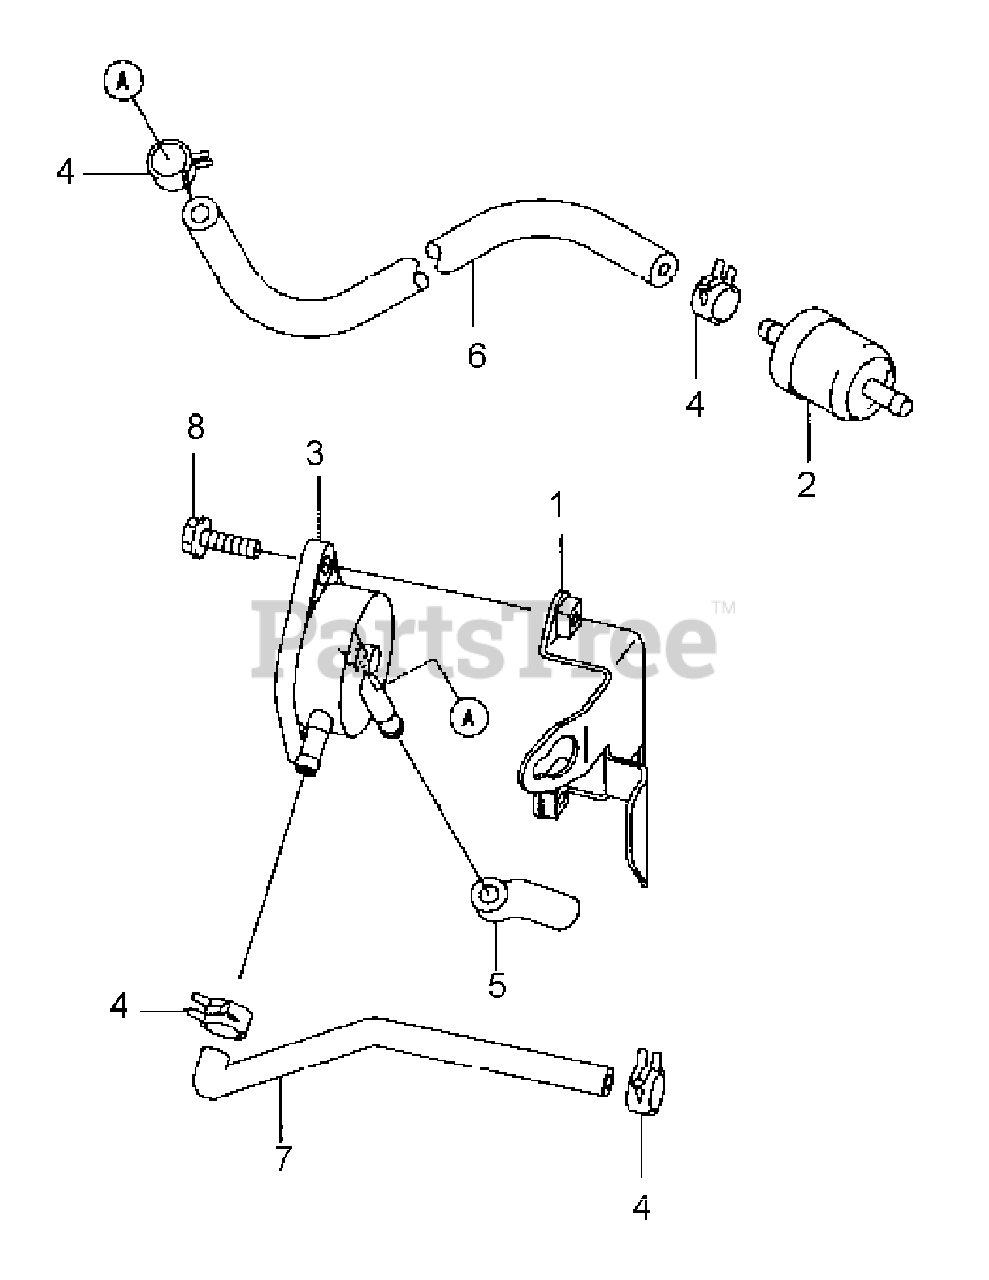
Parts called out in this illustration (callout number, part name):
2	FUEL FILTER
3	FUEL PUMP
4	CLAMP
6	TUBE, 6.35x12.7x160
8	FLANGED BOLT
